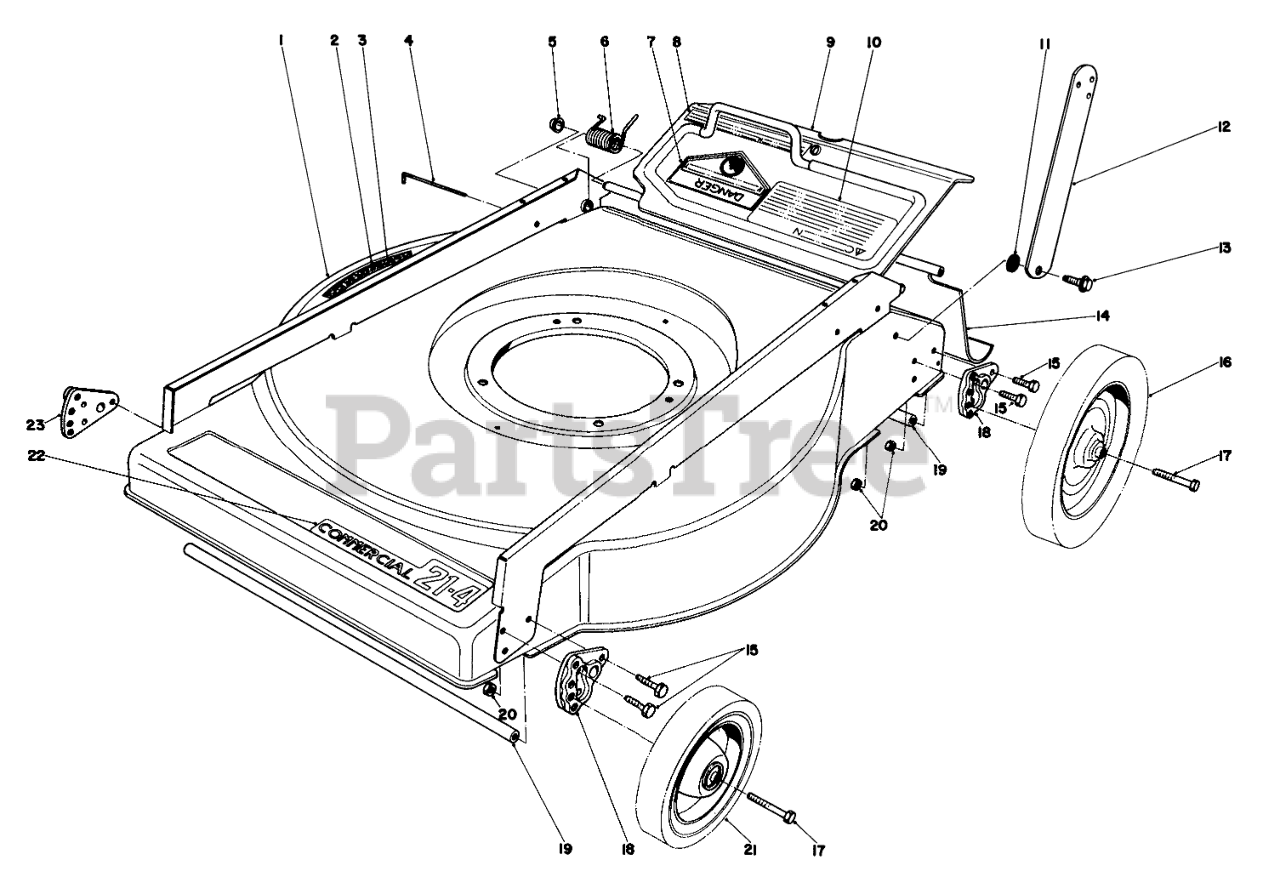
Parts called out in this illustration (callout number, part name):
1	Housing W/Decals (Incl. Ref. #3 & 22)
2	PAD STEP
3	Decal Step Pad
4	SHIELD ROD
5	RETAINER-PUSH ON
6	TORSION SPRING
7	DECAL-DANGER
8	Decal-Door
9	Rear Door (Incl. Ref. #7, 8 & 10)
10	DECAL SAF INST
11	HANDLE LATCH SPACER
12	LONG HANDLE STRUT
13	SCREW-SHOULDER
14	REAR SAFETY SHIELD
15	SCREW-HH
16	WHEEL ASM
17	SCREW-HH
18	Wheel Quadrant (B)
19	Tie Rod
20	NUT-LOCK, CONE
21	WHEEL & TIRE ASM
22	Decal 214 Commercial
23	WHEEL QUADRANT (A)
